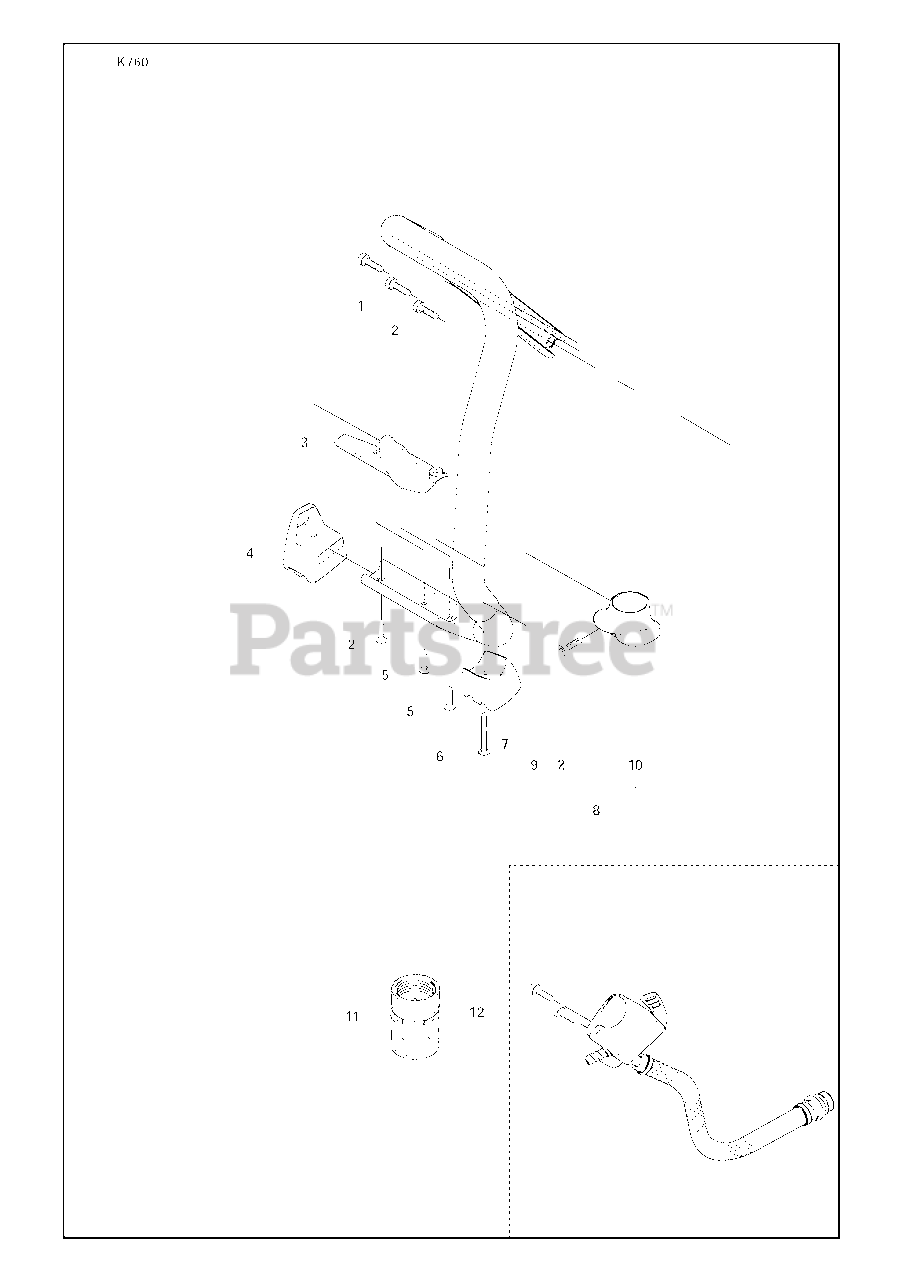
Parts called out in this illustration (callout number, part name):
3	Spring Retainer
4	Ground Support
7	Ground Support
8	Handle
9	Front Handle
11	Coupler
